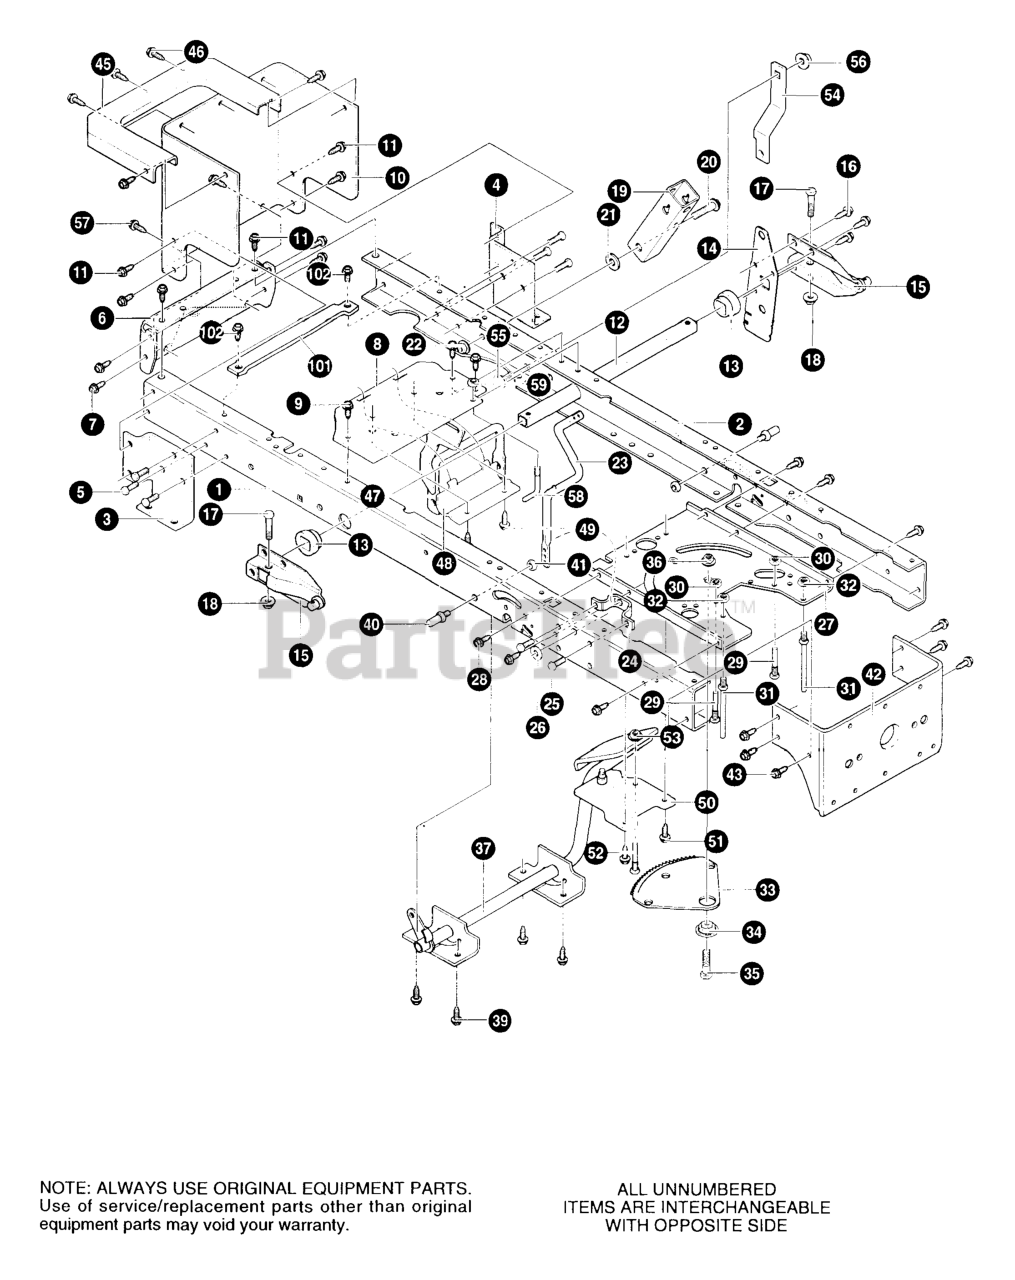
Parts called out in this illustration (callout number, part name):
1	FRAME,RAIL RH
2	FRAME,RAIL LH
3	BRACKET, TRANSAXLE RH **
4	BRACKET, TRANSAXLE LH **
5	SCREW, 5/16-18 x .75 HHWATAP
6	HITCH PLATE
7	SCREW, 5/16-18 x .75 HHWATAP
8	BRACKET, SHIFT RH
9	SCREW 5/16-18X.75HHWATAP
10	PLATE, REAR
11	SCREW, 5/16-18 x 0.75 HHWATAP
12	TUBE, LIFTER
13	BUSHING, LIFT TUBE
14	PLATE-LIFT ARM
15	ASSY, LIFT ARM LEVER
16	SCREW, 5/16-18 x 0.50 WHHTAP (26X49)
17	SCREW, 5/16-24 x 1.25
18	NUT, 5/16-24 NF-2 HEXFLLK
19	BRACKET, PIVOT
20	BOLT, .562X1.563 HHSH 3/8-16
21	FLATWASHER.406ID (17X191)
22	NUT, 3/8-16 HWDFLLK MACK 15X84
23	CRANK, PTO
24	BRACKET, BELL CRANK
25	SCREW, 5/16-18 x .75 HHWATAP
26	FLATWASHER.469X.92X.065
27	PLATE, STEERING
28	SCREW, 5/16-18 x .75 HHWATAP
29	SCREW GUIDE 5/16-18
30	NUT, 5/16-18 HEXWEFLLK WHIZ
31	SCREW - GUIDE
32	NUT, 5/16-18 HEXWDFLLK WHIZ
33	SECTOR GEAR
34	BEARING, SECTOR GEAR
35	SCREW, 5/16-18 x 1.00 HHC
36	NUT, 5/16-8 HKEPS 15X113
37	ASSEMBLY, BRAKE LEVER
39	SCREW, 5/16-18 x 0.75 HHWATAP
40	PIN, THREADED SHOULDER
41	NUT,3/8-16HWDFLWHIZ-LOCK
42	BRACKET, HANGER REAR
43	SCREW, 5/16-18 x 0.75 HHWATAP
45	TOP, REAR PLATE LG SEAT DECK
46	SCREW 10-24X.500TRSEGI
47	YOKE ASSY. TRUNNION
48	CLAMP, TRUNNION PIVOT
49	SCREW, 5/16-18 x 0.75
50	ASSY, IDLER INTERMEDIATE
51	BOLT, 5/16-18X.5
52	SCREW GUIDE 5/16-18
53	NUT, 5/16-18 HEXWDFLLK WHIZ
54	BRACKET, Torque Strap, LH
55	BOLT, 5/16-18X.63 CARR
56	NUT, 5/16-18 WDFLLK
57	SCREW, 5/16-18 x 0.50 HXFLCA
58	SCREW GUIDE
59	NUT, 5/16-18 HXWDFLLK WHIZ PL
101	BRACKET, BATTERY SUPPORT
102	SCREW, 5/16-18 x 0.75 HHWATAP
